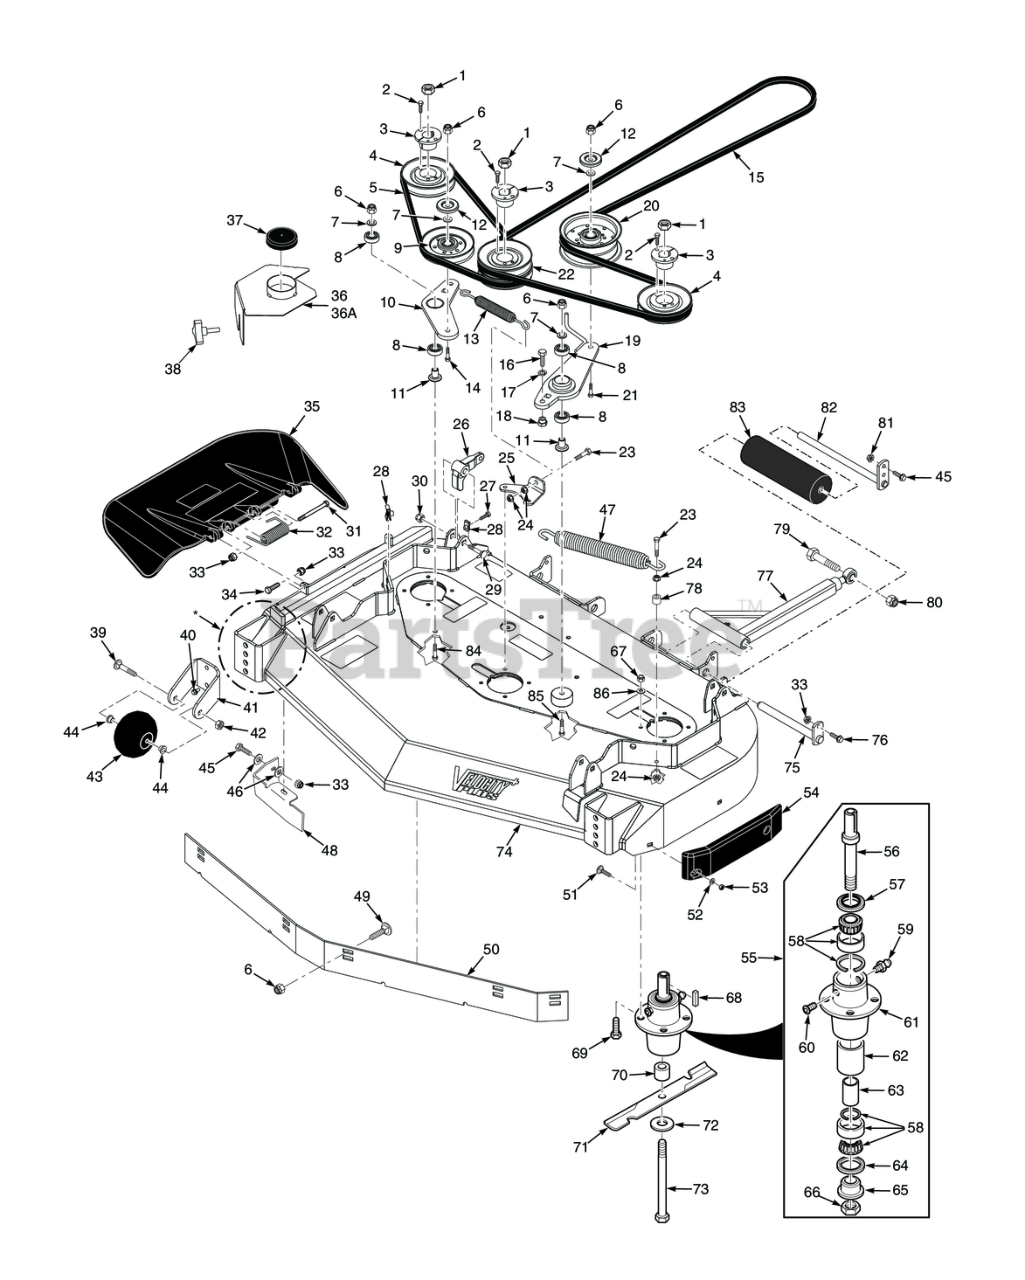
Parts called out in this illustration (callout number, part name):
1	Hex Locknut, Elastic Stop, 3/8-16
2	Bolt, Hex Head 1/4-20 x 1" Grade 8 Black
3	Hub, Tapered 1-1/8" Bore
4	Pulley, 5.13" Dia. - 48V
5	Belt, R.H. Cutter Deck
6	HEX NUT, ELASTIC STOP LOCK, 3/8-16
7	Flatwasher, 3/8 (.391 x .938 x .105 HD) Grade 8
8	BEARINGS, BALL, NEUTRAL RETURN
9	IDLER PULLEY, "V" GROOVE
10	ldler Arm Assembly, R.H. Drive
11	Pivot, Idler Short
12	Quick Pin, 5/16" Dia.
13	Spring, Idler R.H.
14	Capscrew, Hex Head 3/8-16 x 2.0"
15	Belt, Cutter Deck Drive (48V)
16	Bolt, Hex Head 7/16-14 x 1"
17	Lockwasher, 7/16� Spring
18	Boss, Spring Anchor - LH
19	Idler Arm Assy.
20	Pulley, Idler 5" Dia.
21	Bolt, Hex Head 3/8-16 x 3" - 52"
22	Pulley, Double Groove
23	Bolt, Hex Head 3/8-16 x 1-1/2" Grade 8 Black
24	NUT, 3/8-16 SERRATED FLANGE HEX HEAD
25	Bracket, Spring Anchor RH (48V)
26	Lever, Deck Level
27	Bolt, Hex Head 3/8-16 x 2" Special Lock
28	U-Nut, 3/8-16 (short)
29	Bolt, Carriage 7/16-14 x 2-1/4"
30	HEX LOCKNUT, ELASTIC STOP, 7/16-14
31	Bolt, 5/16-18 x 4-3/4" Hex Head
32	Spring, Discharge Chute
33	HEX NUT, ELASTIC STOP LOCK, 5/16-18
34	Bolt, Hex Head 5/16-18 x 1-1/2" - Front
35	Discharge Chute Assembly - 48V
36	Belt Cover Weldment RH
36	Belt Cover Weldment LH
38	Knob, w/stud 3/8-16 x 1-1/4"
39	Bolt, Hex Head 3/8-16 x 3-1/2"
40	Capscrew, 3/8-16 x 1.0" Serrated Flange Hex Hd
41	Bracket, Anti-Scalp Wheel
42	Bolt, Hex Head 3/8-16 x 1" Ser. Flg.
43	Bolt, Carriage 3/8-16 x 4"
44	Bushing, .376" I.D. Oilite
45	Bolt, Heax Head 5/16-18 x 1" (48V / 52V)
46	Flatwasher, 5/16-.375 x .875 x .083 (35BV & 37BV-EFI)
47	Spring, L.H. Deck Drive
48	Turbo Baffle - 48V / 52V
49	Carriage Bolt, 3/8-16 x 1.0"
50	Baffle Custom-Cut, 48V (7-Position)
51	Bolt, 5/16-18 x .75 RHSN Carriage
52	Flatwasher, 5/16-.344 x .688 x .065 (48V / 52V)
53	Nut, Center Lock, 5/16-18(32)
54	Pad, Deck Wear
55	Cutter Spindle Assembly
56	Spindle Shaft, Tapered Brng
57	SEAL, 2.00 O.D. X 1.50 BORE
58	Tapered Bearing Set (Two Bearings W/Race)
59	GREASE FITTING, STR. 1/4-28 SELF TAP.
60	RELIEF FITTING, TAPERED BEARING SPINDLE
61	Housing, Spindle
62	Spacer, Outside, Cutter Spindle
63	SLEEVE, CUTTER SPINDLE
64	Seal, 2.00" O.D. x 1.625" Bore
65	SPINDLE BUSHING, BOTTOM
66	Nut , Spec ial 1 -1/ 1 6 - 1 8
67	Lock Nut, 5/16-18 Elastic Stop Grade 8
68	Key, 1/4 x 1/4 x 2.0"
69	Bolt, Hex Head 5/16-18 x 1-3/4" Grade 8
70	Spacer, Spindle Bottom
71	Cutter Blade, 16-1/2" (48V)
72	Flatwasher, 5/8-.688 x 1-3/4 x .134 HD
73	BOLT, HEX HEAD, 5/8-11 X 9-1/2 GR.5
74	Cutter Deck Velocity Plus
75	Shaft Weldment, Pusharm
76	Bolt, Heax Head 5/16-18 x 1" (48V / 52V)
77	Push Arm (Includes 64,60,62)
78	SPACER, IDLER
79	BOLT, HEX HEAD 5/8-11 X 4-1/2"
80	HEX LOCKNUT, ELASTIC STOP, 5/8-11
81	Nut, Flange Head Elastic Stop 5/16-18
82	Shaft Weldment, Guide Roller
83	Wheel, Anti-ScalpRelief Fitting, Tapered Spindle
84	Bolt, Hex Head 3/8-16 x 2-1/4" - 61"
85	Capscrew, Hex Head 3/8-16 x 3.25"
86	Lockwasher, 5/16 (.317 x .586 x .078) Helical Spring
